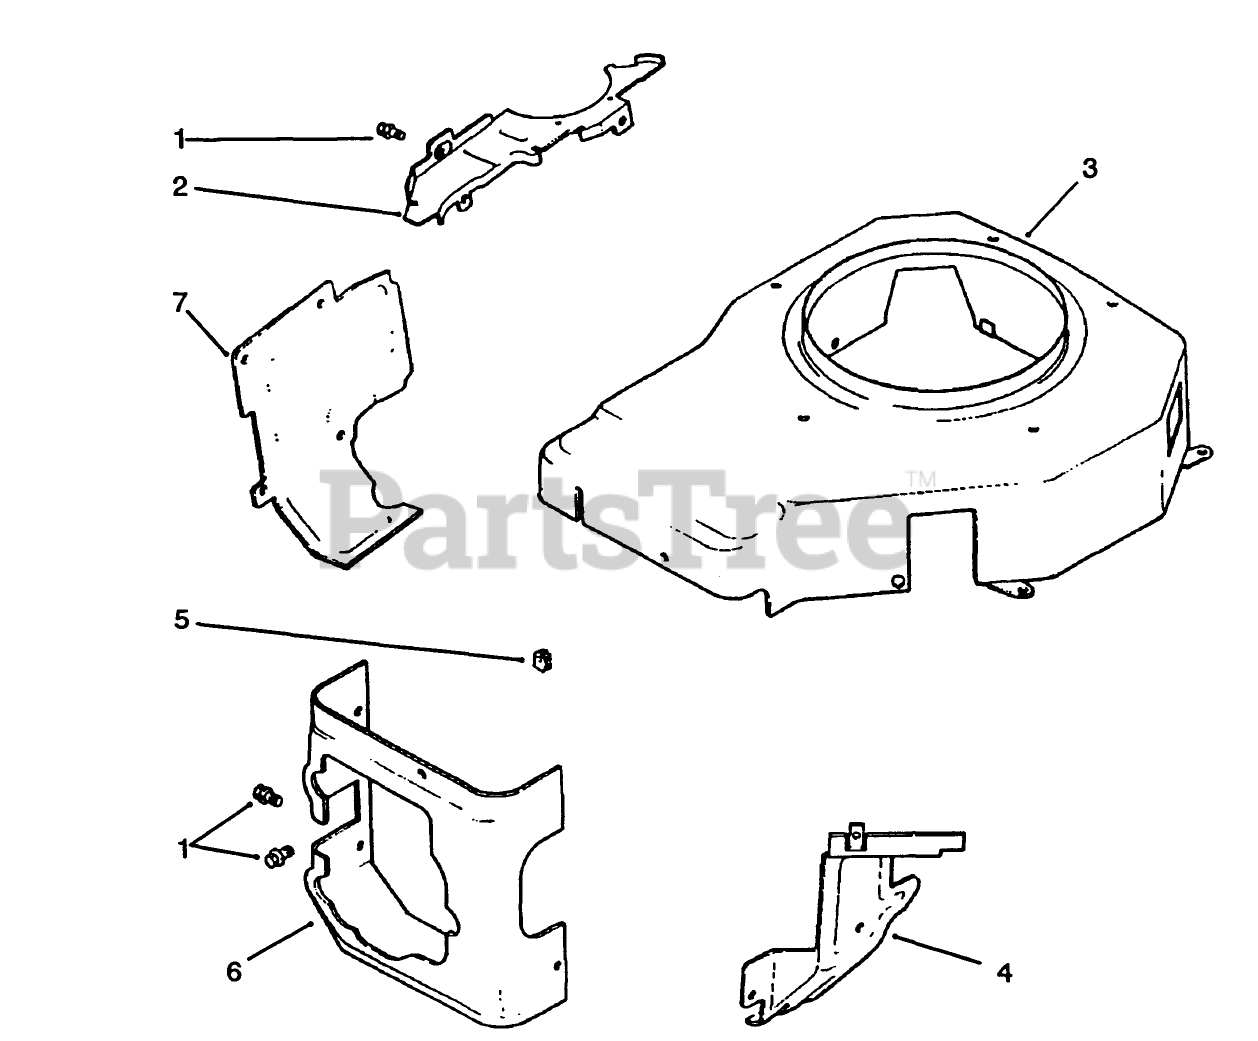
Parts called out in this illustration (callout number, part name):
2	Plate-Blower Housing (Only On: 72042,72043,72062,72063)
3	Housing-Blower (Only On: 72042,72043,72062,72063)
4	Baffle-Carburetor (Only On: 72042, 72043, 72062, 72063)
5	Grommet-Blower Housing (Only On: 72042, 72043, 72062, 72063)
6	Baffle-Cylinder Head (Only On: 72042, 72063, 72062, 72043)
7	Baffle-Cylinder Barrel (Only On: 72042, 72063, 72062, 72043)
